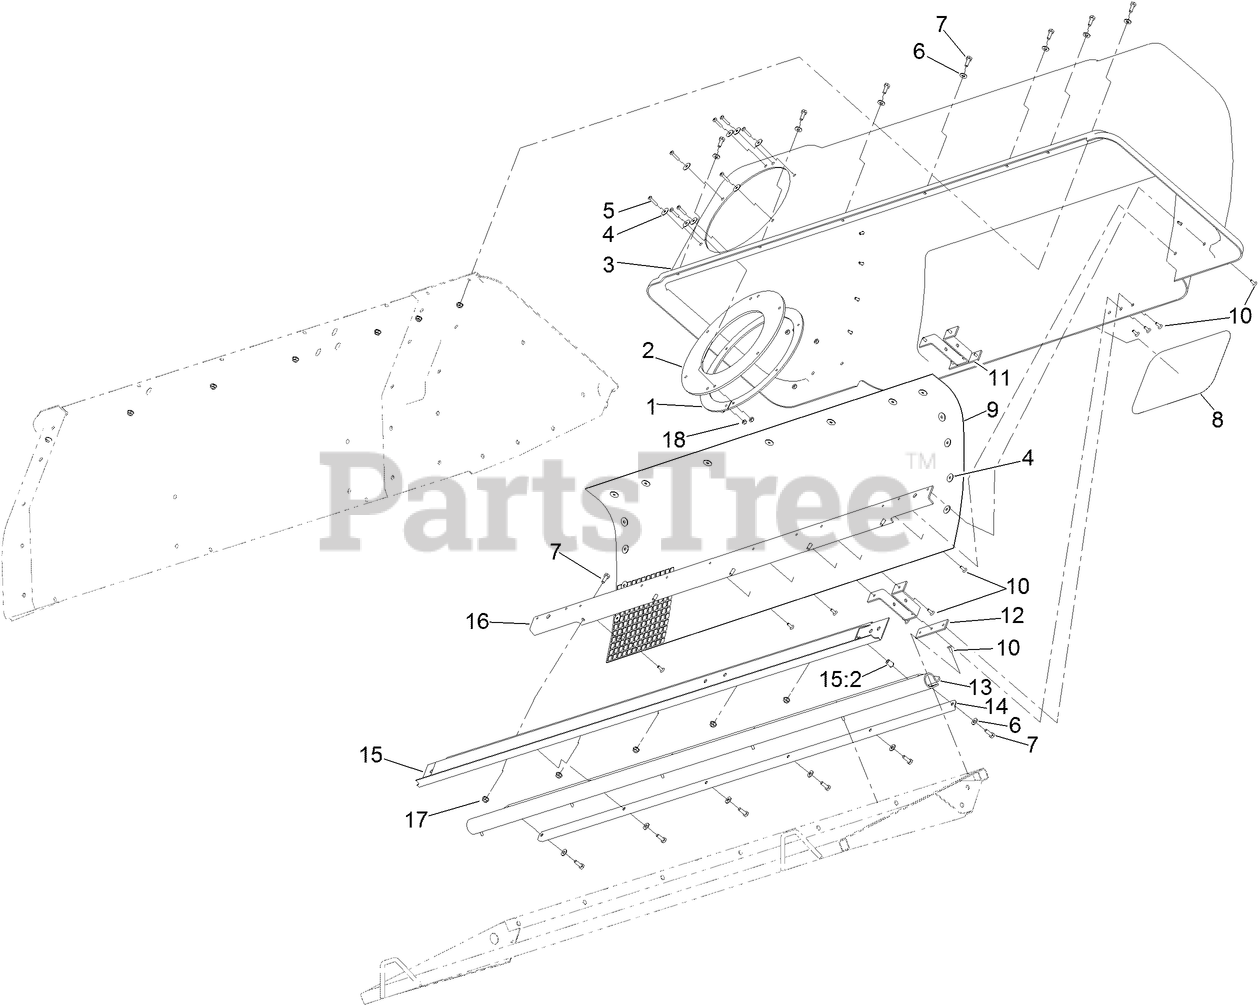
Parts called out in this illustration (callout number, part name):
1	CLAMP-SEAL
2	SEAL-TUBE
3	HOOD ASM
4	WASHER-FLAT
5	SCREW-PPH
6	WASHER-FLAT
7	SCREW-HH
8	DECAL
9	SCREEN-BAGGER
10	RIVET-BLIND
11	BRACKET-MOUNT
12	PLATE-LATCH, REINFORCEMENT
13	SEAL-DOOR HINGE
14	STRAP-HOLD DOWN
15	REAR CROSSMEMBER ASM
15:2	NUT-CLINCH
16	SUPPORT-SCREEN
17	NUT-HF
18	NUT-LOCK, NI
